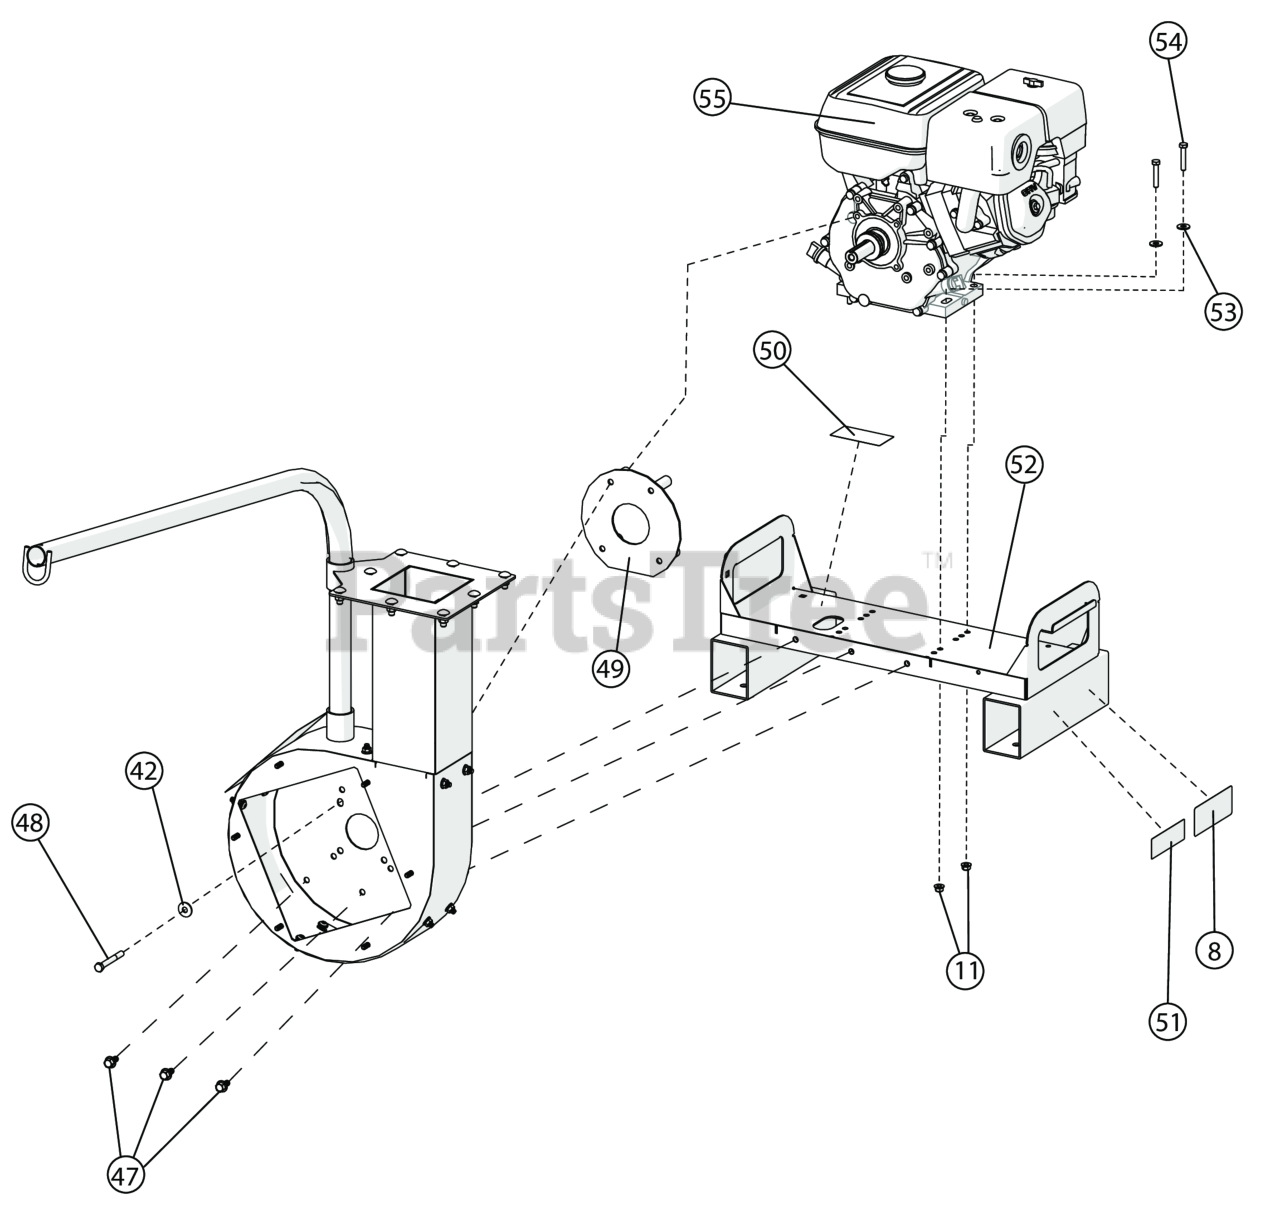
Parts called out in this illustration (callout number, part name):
8	LABEL WARNING ENGINE OVERHEAT
11	NUT-HEX-NYLK, FLG .3125-18 ZP
42	WSHR-STL, BLV, .386" X 1.063" X .082" MZ
47	SER HEX WASHER 3/8" - 16
48	SCREWCAP 3/8"-16X3" HCS ZP
49	SPACER ENGINE WA DL12/13
50	LABEL WARNING SECURE
51	LABEL SPARK ARRESTOR
52	BASE ENGINE WA
53	WASHER 5/16" FLATWASHER Z/P
54	SCREWCAP 5/16"-18X1 3/4" HCS ZP
55	ENGINE HONDA GX390 13 HP
